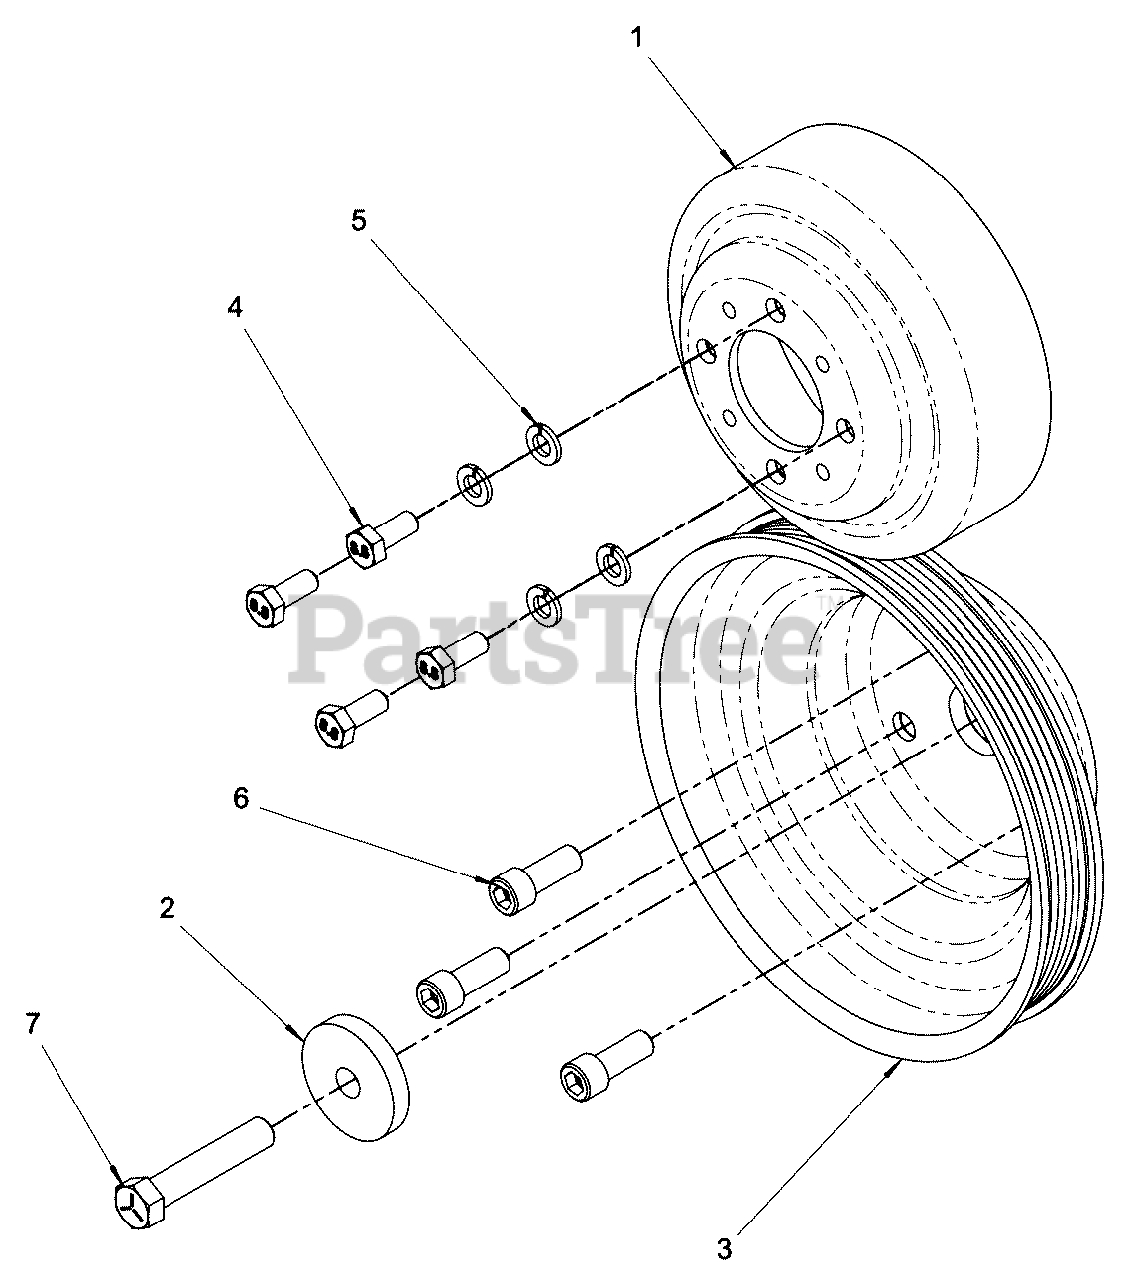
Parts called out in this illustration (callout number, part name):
2	WASHER, C/SHAFT
3	PULLEY, CRANK
4	BOLT
5	WASHER, LOCK
6	BOLT
7	BOLT
